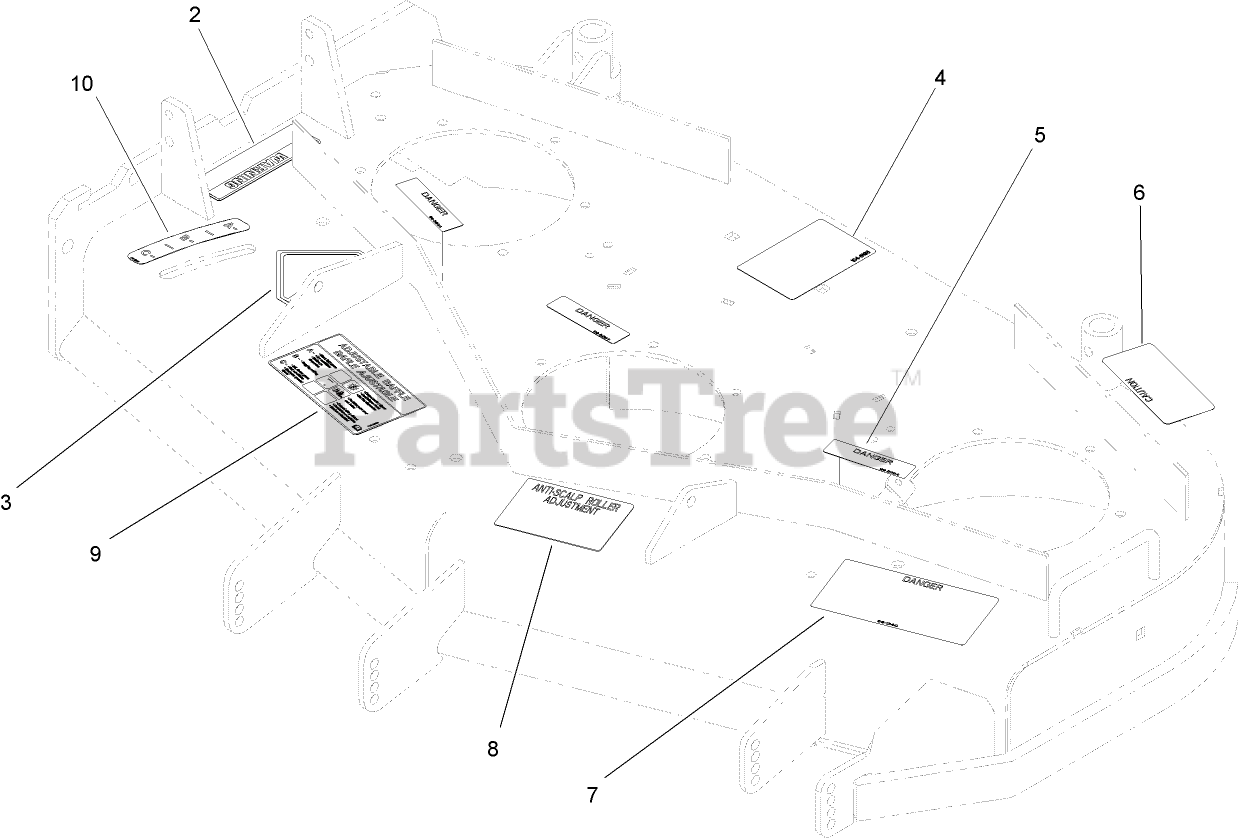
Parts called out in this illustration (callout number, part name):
2	DECAL-WARNING
3	DECAL-DANGER
4	DECAL-ROUTING, BELT
5	DECAL-COVER, MISSING
6	DECAL-TORQUE
7	DECAL-DANGER, THROWN OBJECT
8	DECAL-SCALP, ANTI
9	DECAL-ADJUSTMENT, BAFFLE
10	DECAL-SETTING, BAFFLE
